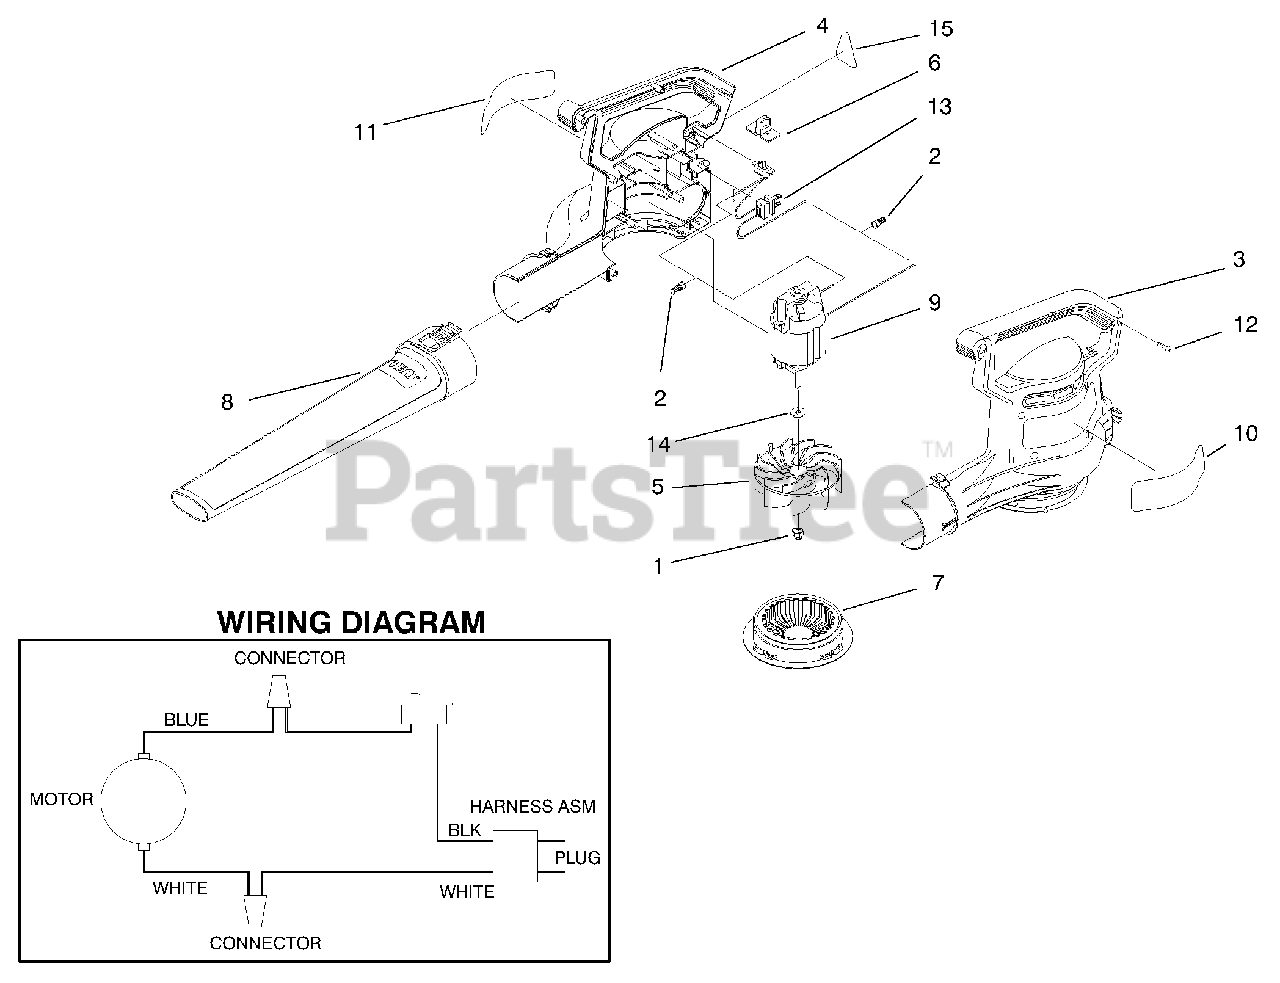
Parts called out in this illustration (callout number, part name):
1	Nut-Hex Lock
2	Connector-Wire Nut
3	Housing-LH
4	Housing-RH
5	Impeller
6	Cover-Switch
7	Cover-Inlet
8	Tube-Blower
10	Decal-Logo
11	Decal-Label
13	Harness Assembly
15	Decal-Information
